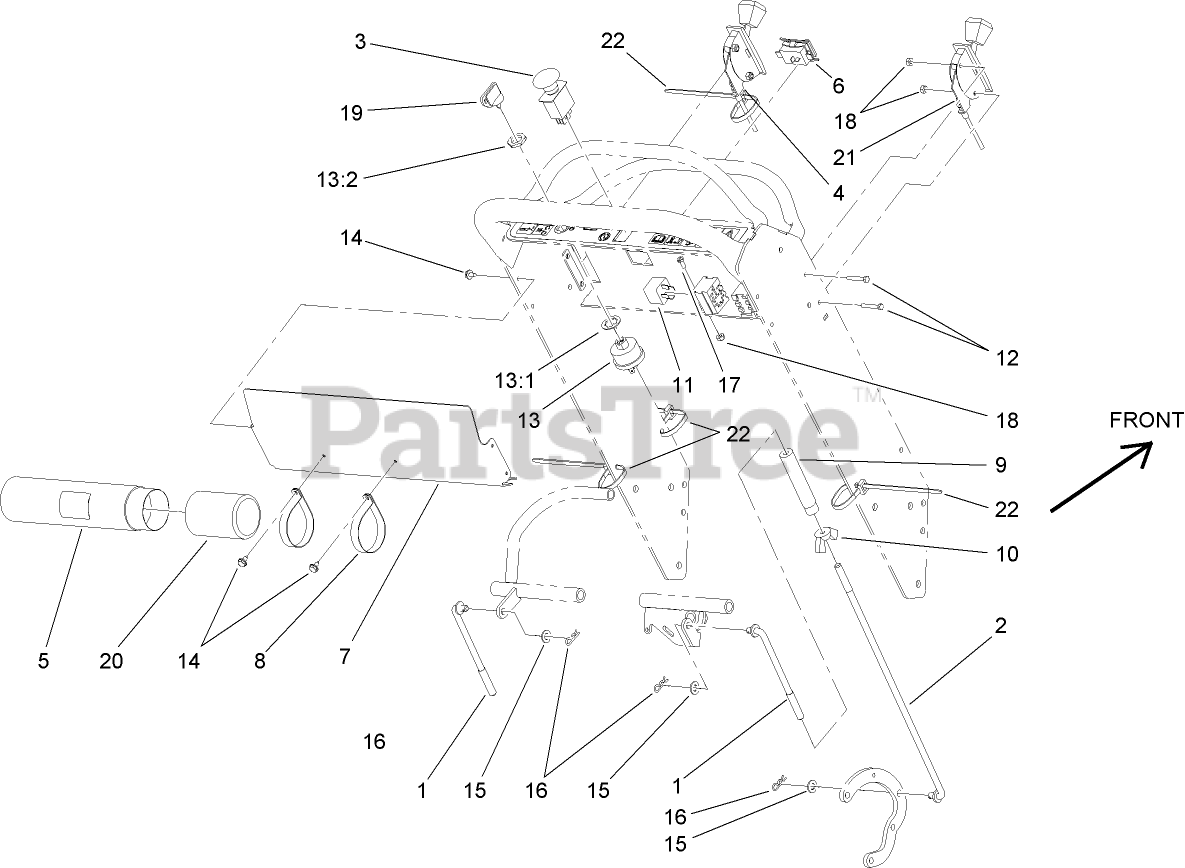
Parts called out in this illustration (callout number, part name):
1	ROD-CONTROL, UPPER
2	ROD-CONTROL, LOWER
3	SWITCH-PTO, ON-ON-(ON)
4	CABLE-THROTTLE
5	TUBE-MANUAL
6	HOURMETER
7	COVER-PANEL, CONTROL
8	CLAMP-R
9	TURNBUCKLE
10	NUT-WING
11	RELAY
12	SCREW-HH
13	Key Switch ASM
13:1	WASHER-TOOTH, INTERNAL
13:2	NUT-HH
14	SCREW-HWHTF
15	WASHER-PLAIN
16	PIN-COTTER
17	SCREW-SHH
18	NUT-LOCK, NI
19	KEY-IGNITION
20	CAP-HOUSING
21	CABLE-CHOKE
22	TIE-CABLE
